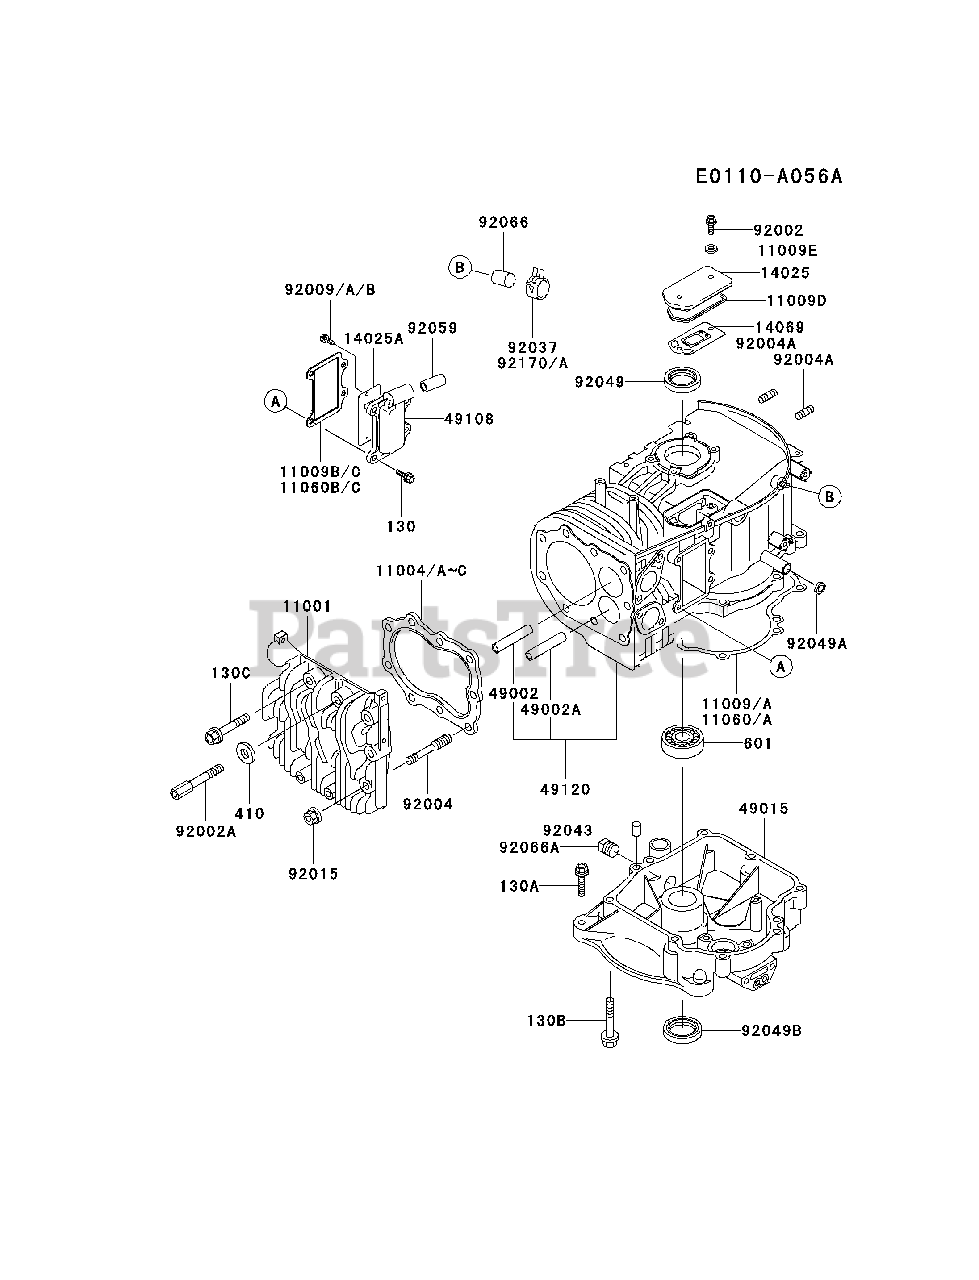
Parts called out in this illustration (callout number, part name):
130	BOLT-FLANGED
130A	BOLT-FLANGED
130B	BOLT-FLANGED
130C	BOLT-FLANGED
410	W-PLAIN-S
601	BEARING,BALL
